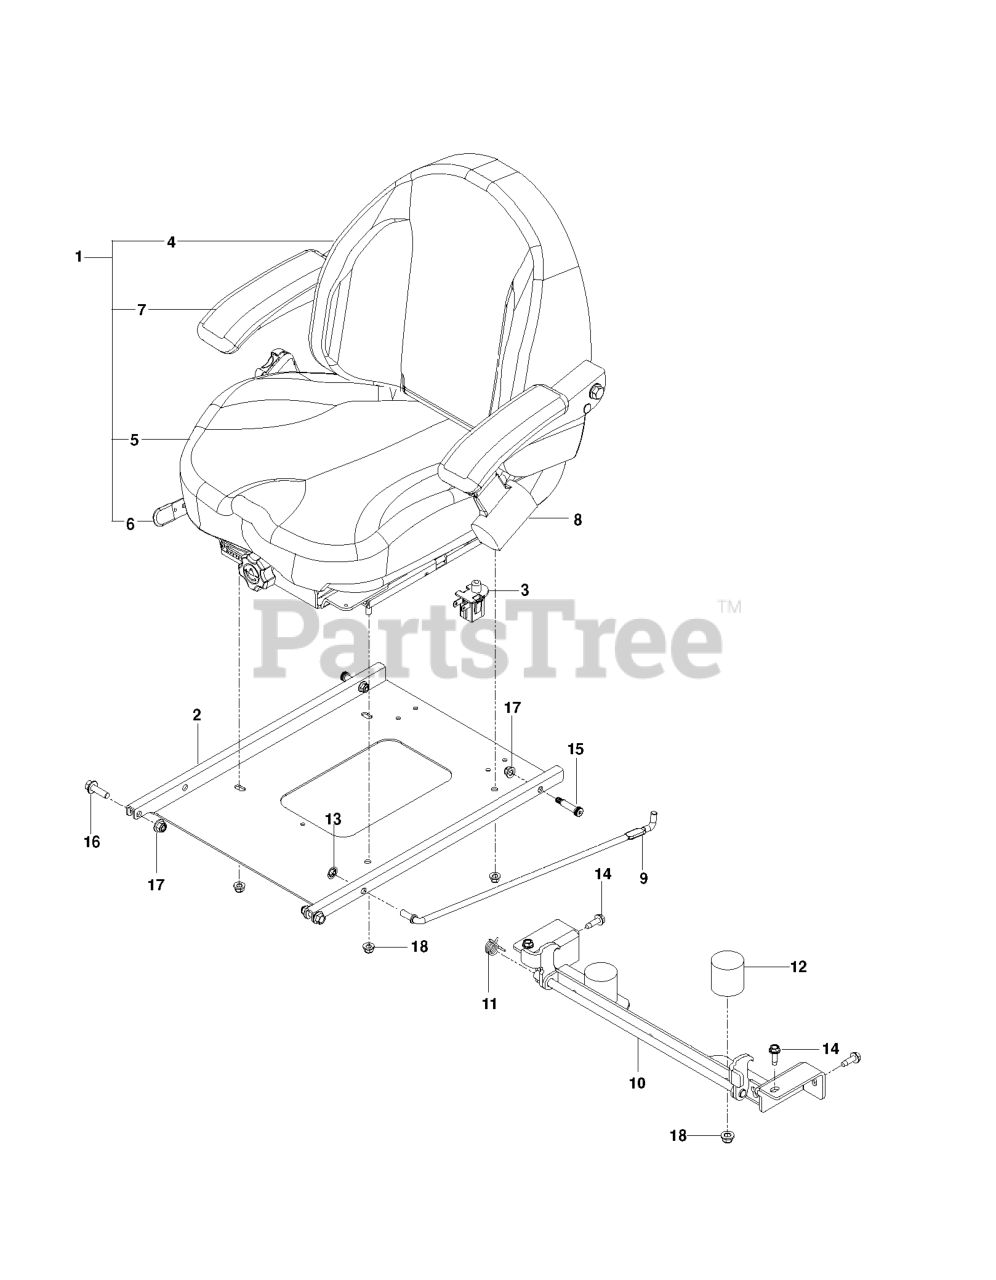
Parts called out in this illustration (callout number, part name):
1	Seat Assy
2	PAN, SEAT, BLACK
3	SEAT SWITCH
4	COVER, BACK
5	COVER KIT, CUSHION
7	ARMREST, LT
8	SEAT BELT, RETRACTABLE
10	LATCH.SEAT.BLACK
11	SPRING, TORSION
12	BUMPER, RUBBER
13	NUT 3/8 PALNUT RTNG BLK PHOS
14	RP BLT 5/16-18 X 1 THRD FORM D
15	BOLT, SHOULDER 3/8 X 1.25
16	HHFS 3/8-16 X 1.25 GD 5
17	NUT 3/8-16 HEX FLG NYLOC ZD
18	5/16-18 NYLOC FLANGE NUT
